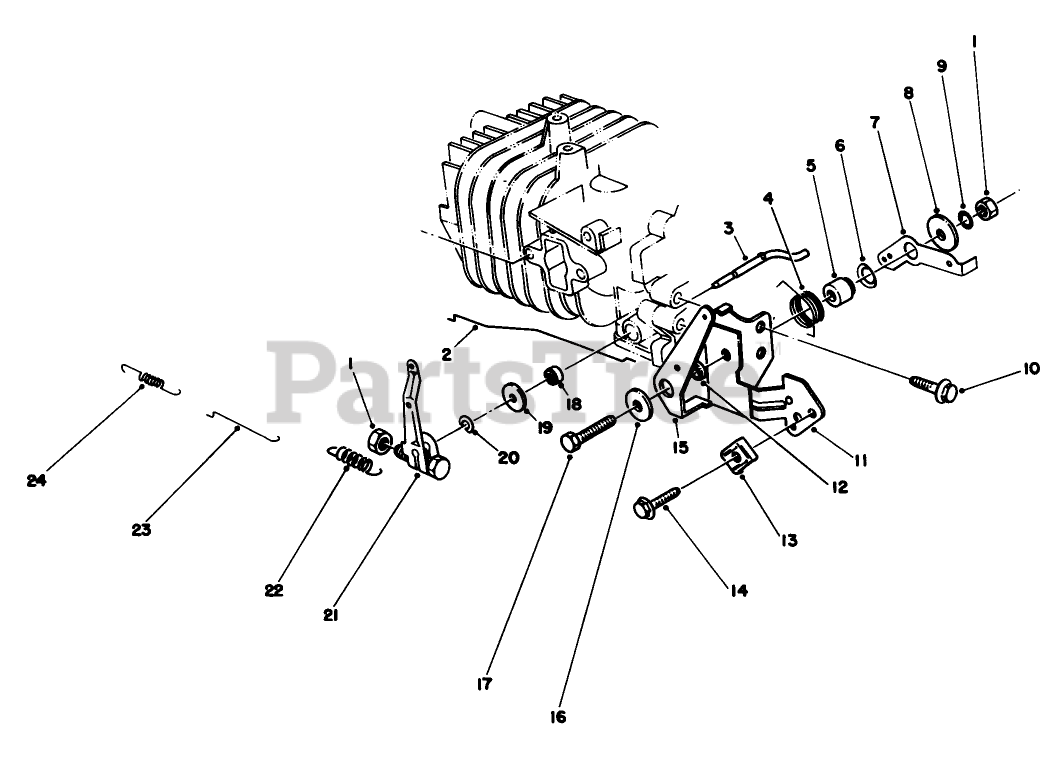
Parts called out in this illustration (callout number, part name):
4	SPRING-CHOKE LEVER
7	LEVER-SPRING, GOVERNOR
8	WASHER
9	LOCKWASHER
11	BRACKET-THROTTLE, CONTROL
12	SPACER-CHOKE LEVER
13	CLAMP
18	SEAL-OIL
19	WASHER
22	SPRING-GOVERNOR
23	ROD-CARBURETOR
24	SPRING
